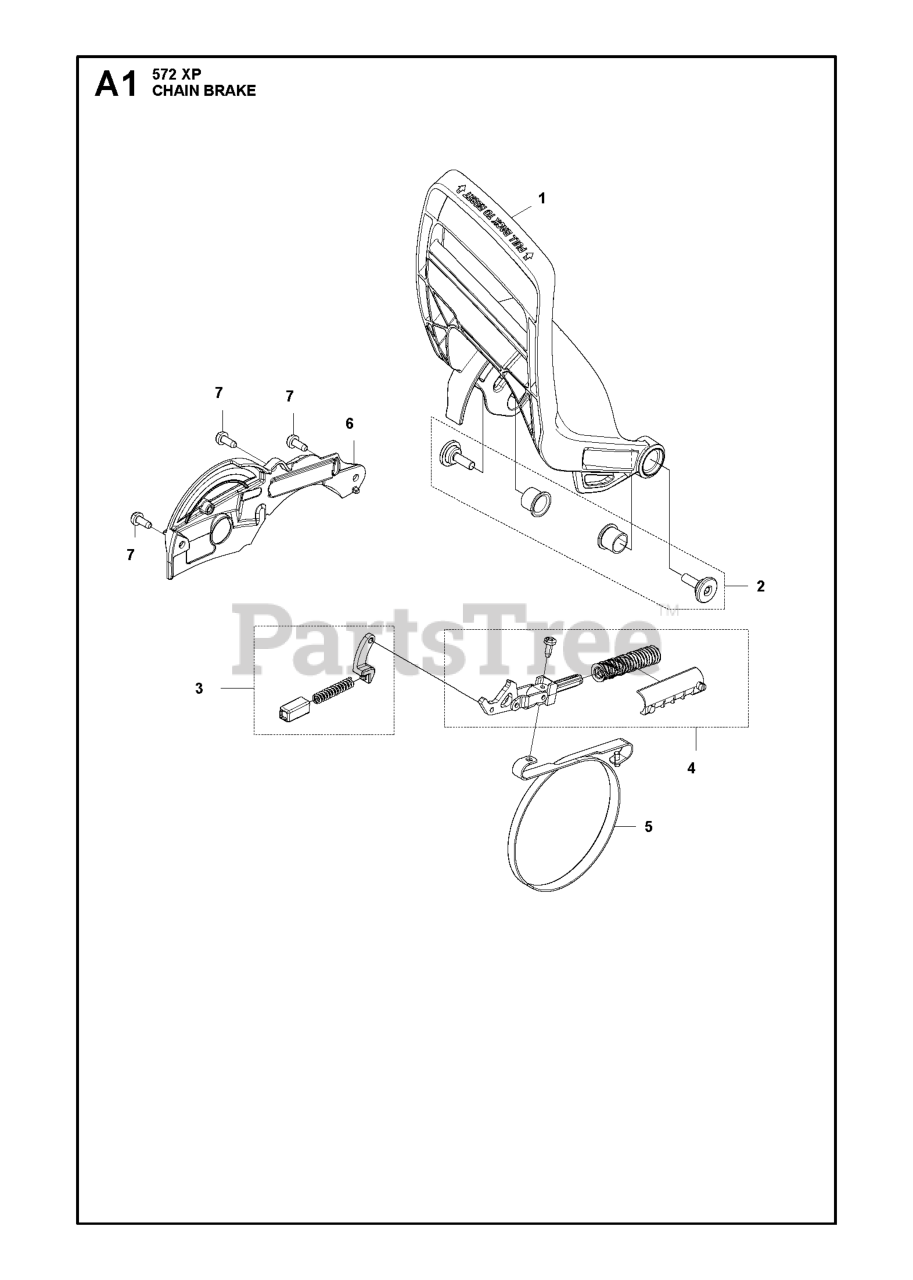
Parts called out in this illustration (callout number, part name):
1	HAND GUARD H565/H572
2	HAND GUARD BUSHING AND SCREW K
3	CHAIN BRAKE LOCK KIT H565/H572
4	KNEE JOINT KIT H565/H572
5	BRAKE BAND
6	COVER BRAKE
7	SCREW HEXALOBULAR PAN HEAD M4
